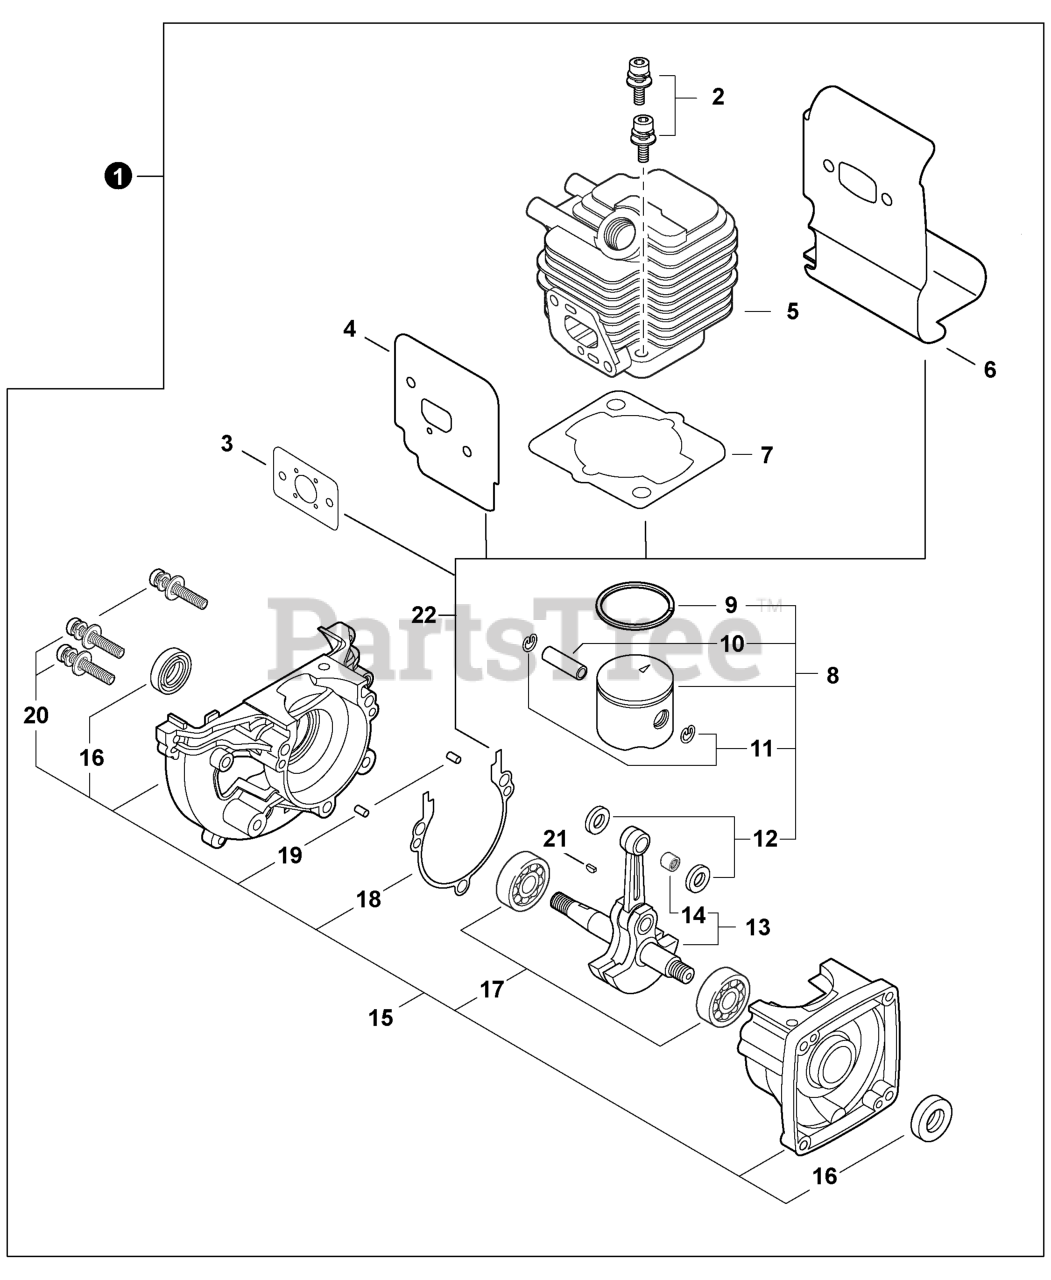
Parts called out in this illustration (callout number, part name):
1	SHORT BLOCK
2	BOLT 5x22
3	GASKET, INTAKE
4	HEAT SHIELD, INTAKE
5	CYLINDER
6	HEAT SHIELD, EXHAUST
7	GASKET, CYLINDER
8	PISTON KIT
9	RING, PISTON
10	PIN, PISTON 8
11	RING, SNAP
12	WASHER, THRUST
13	CRANKSHAFT ASSY
14	BEARING, NEEDLE 8
15	CRANKCASE KIT
16	SEAL, OIL 12
17	BEARING, BALL 6201
18	GASKET, CRANKCASE
19	PIN, LOCATING 4x8
20	BOLT 5x28
21	KEY, WOODRUFF
22	GASKET KIT: ENGINE, INTAKE, EXHAUST
